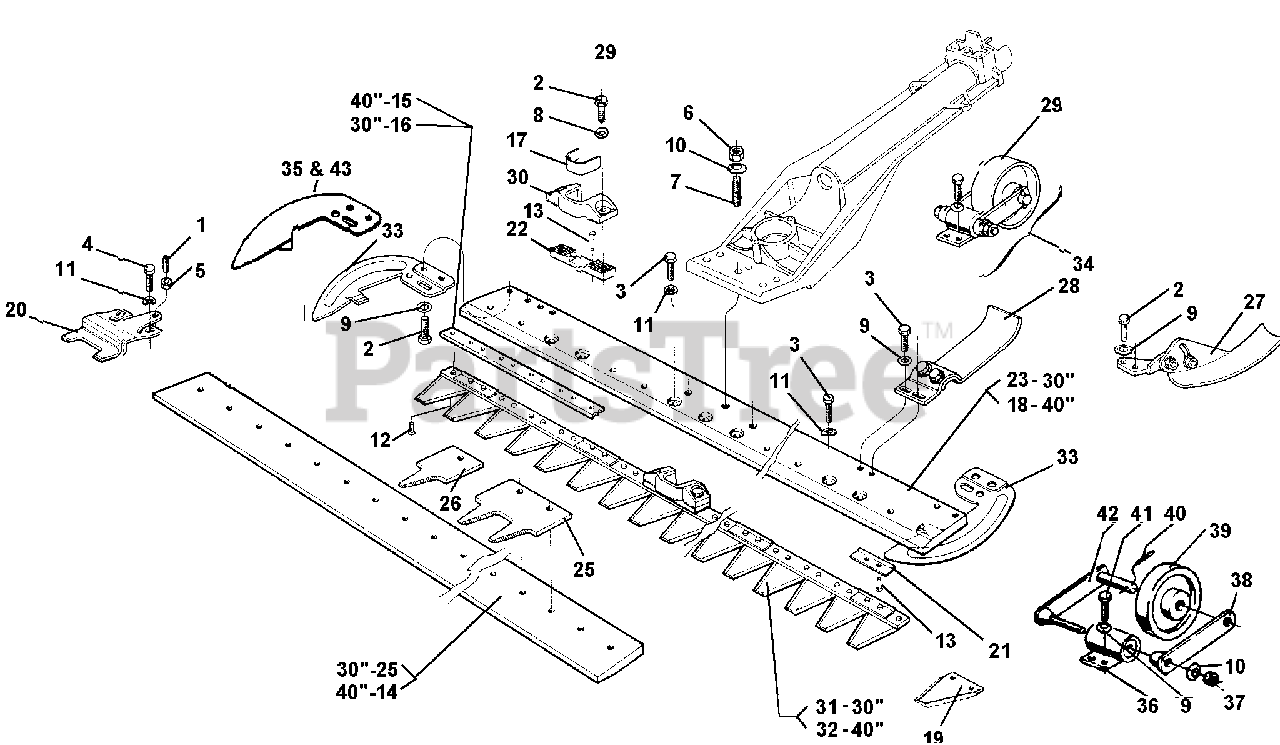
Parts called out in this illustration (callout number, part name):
1	SCREW M8 X 14
2	SCREW M8 X 16
3	SCREW M8 X 25
4	SCREW M8 X 35
6	SELF LOCKING NUT
8	WASHER, FLAT 8.4
9	SUPER WASHER 8 DIN 6796
10	SUPER WASHER 10 DIN 6796
11	WASHER, LOCK 8.4
12	RIVET TSV 6.5 X 13
13	RIVET TSV 6.5 X 16
14	SLIDE FOR COMBO BAR 1.00 M
15	BLADE STRIP
18	CENTER, CUTTER BAR COMBO 1 M
19	SECTION F. NARROW SCORED BLAD
21	PLATE FOR CLEANING
22	BLADE COUPLING PLATE
23	CENTRAL BAR 0.80 MT.
25	DOUBLE FINGER
26	SINGLE FINGER
27	SKID NO LONGER AVAILABLE
28	SLIDE WITH SCREWS
29	WHEEL D = 100
30	BLADE COUPLING
31	SCORED BLADE WITH COUPLING
32	SCORED BLADE WITH COUPLING
33	END GUARD-COMBO BAR (PR)
34	CUTTER BAR WHEELS - PAIR
35	LH END GAURD NLA USE REF #33
36	WHEEL SUPPORT
39	WHEEL D=100
40	PIN, LOCKING
42	SUPPORT WITH PIN
43	RH END GAURD NLA USE REF #33
